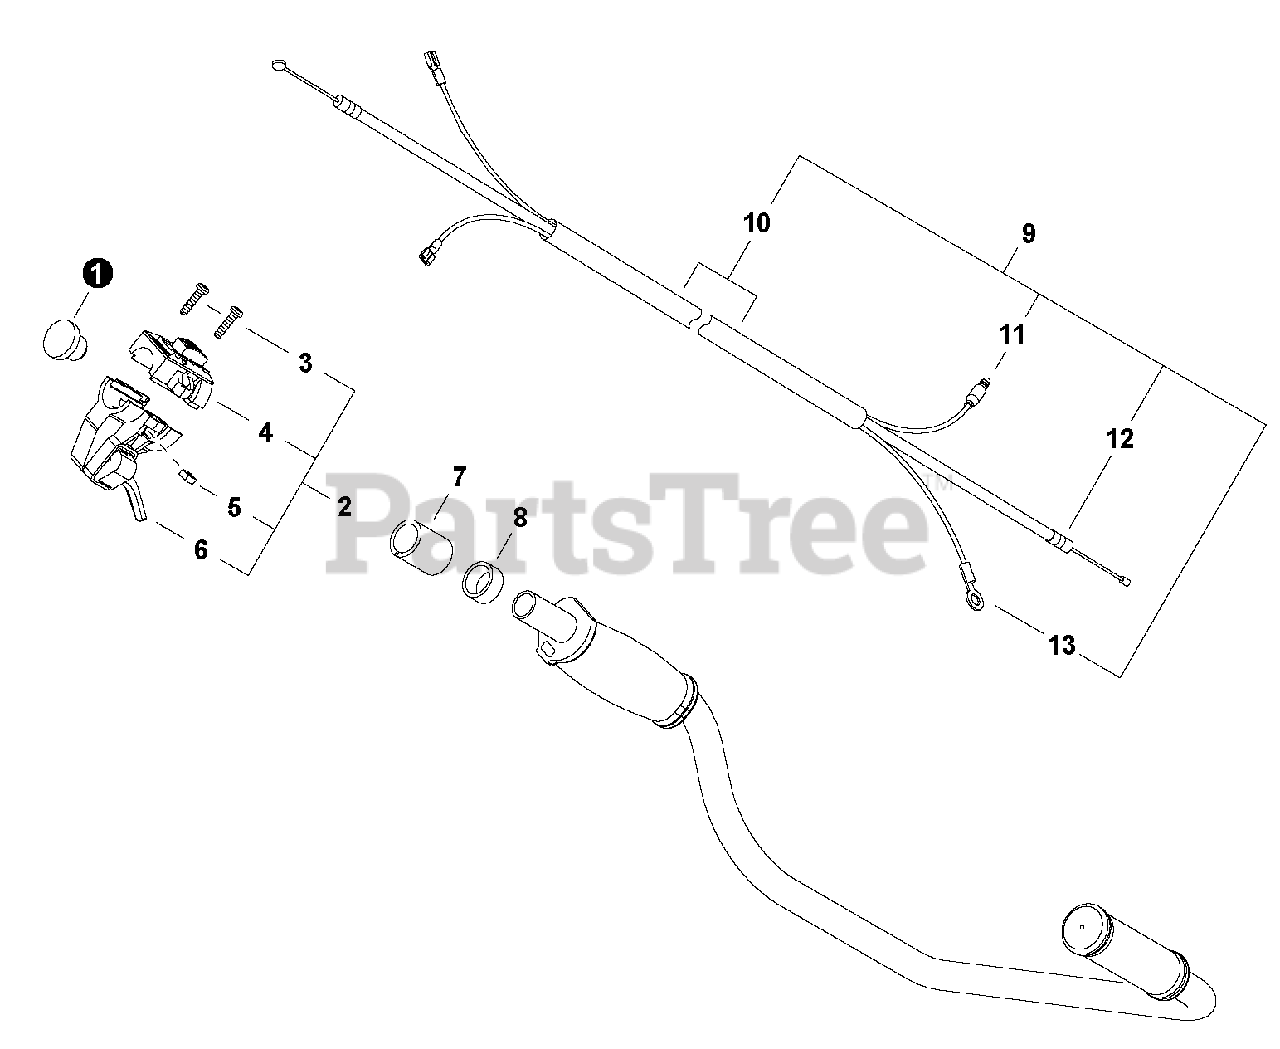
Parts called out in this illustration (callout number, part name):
2	Throttle Control Assy
4	Switch, On-off
5	Nut
6	Control, Throttle
9	Cable Assy, Throttle
11	Lead - Red
12	Cable, Throttle
13	Lead - Black
